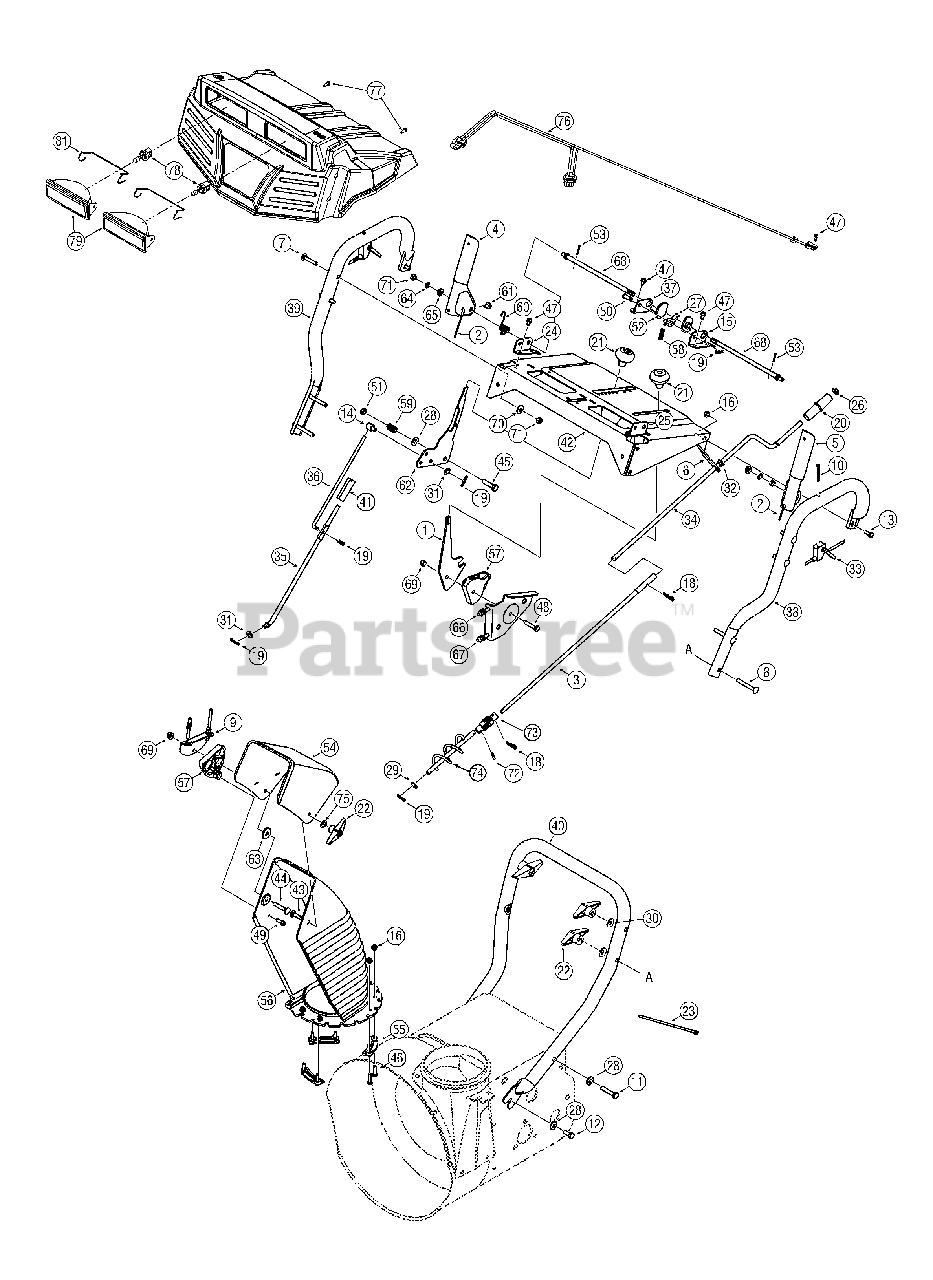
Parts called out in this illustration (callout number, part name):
1	Chute Tilt Handle
2	Cable Ass’y (Auger/Drive)
4	Engage Handle RH Black
5	Engagement Handle LH
6	Black Upper Chute Crank Support
7	Carriage Bolt 5/16-18 x 1.75" Lg.
8	Carriage Bolt 5/16-18 X 2.50
10	Screw, #10-24 x 1.75
11	Hex Screw 3/8-16 x 2.0 Gr. 5
12	Hex TT Screw 3/8-16 x .75
13	Hex Cap Bolt 1/4-20 x .75" Lg.
14	Adjustment Ferrule
15	LH Handle Support Brkt. 5/8"
16	Hex L-Flanged Nut 1/4-20 Gr. F Nylon
18	Internal Cotter Pin
19	Int. Cotter Pin .072 x 1.13" Lg.
20	Knob 1.0 x 3.2
21	Shift Knob
22	Knob
23	Cable Tie
24	RH Handle Support Brkt. 3/8"
26	Push Nut 3/8" Rod
27	Cam Lock Pawl
28	Cupped Washer .375 ID x .870 OD x .063
29	Flat Washer .406" I.D. x .75" O.D.
30	Cupped Washer .345 ID x .88 OD x .06
31	Flat Washer .34 ID x .688 OD x .065
32	Plastic Bushing .380 ID
33	Steering Trigger
34	Upper Chute Crank Assembly
35	Lower Shift Rod
36	Upper Shift Rod
37	RH Handle Support Brkt. 5/8"
38	Upper Handle LH - Black
39	Upper Handle RH - Black
40	Lower Handle - Black
41	Connector - Shift Rod
43	Carriage Bolt 5/16-18 x 1.00" Lg
44	Carriage Bolt 5/16-18 x 1.75" Lg.
45	Hex Scr 3/8-24 x 1.50
46	Screw 1/4-20 x 1.0
47	Hex Wash S-Tapp Scr 1/4-20 x .50
48	Hex Bolt 5/16-18 x 1,50" Lg. Gr. 5
49	Hex Tapp Scr 1/4 x .75" Lg.
50	Clevis Pin .31 Dia. x 1.0" Lg.
51	Hex Nut 3/8-16 Gr. 5 Nylon
52	Cam Handle Lock
53	Cotter Pin 3/32 x .75
54	Upper Chute
55	Chute Flange Keeper
56	Lower Chute
57	Cable Guide
58	Compression Spring .62 OD x 6.12" Lg.
59	Compression Spring .38 ID x .88 Lg
60	Torsion Spring
61	Rubber Bumper
62	Shift Lever
63	Flat Washer .344 ID x 1.125 OD x .125
64	L-Wash 5/16 ID
65	Flat Washer (special) .350 sq. x .72 x .134
66	Chute Control Cable 66"
67	Chute Control Cable w/clip
68	Cam Rod
69	Hex L-Flanged Nut 5/16-18 Gr. F Nylon
70	Flat Washer .349 ID x .879 OD x .063
71	Hex Patch L-Nut 5/16-18
72	Spiral Pin .156 Diam x .80" Lg.
73	Joint Block Ass'y
74	Chute Crank Assembly
75	Flat Washer .349 ID x .879 OD x .063
76	Wire Harness
77	Hex Tapp Wash Hd. Scr. #10 x 5/8
78	Bulb #890, 12 V, 27 Watt
79	Headlight Housing
80	Black Handle Panel
81	Retainer
